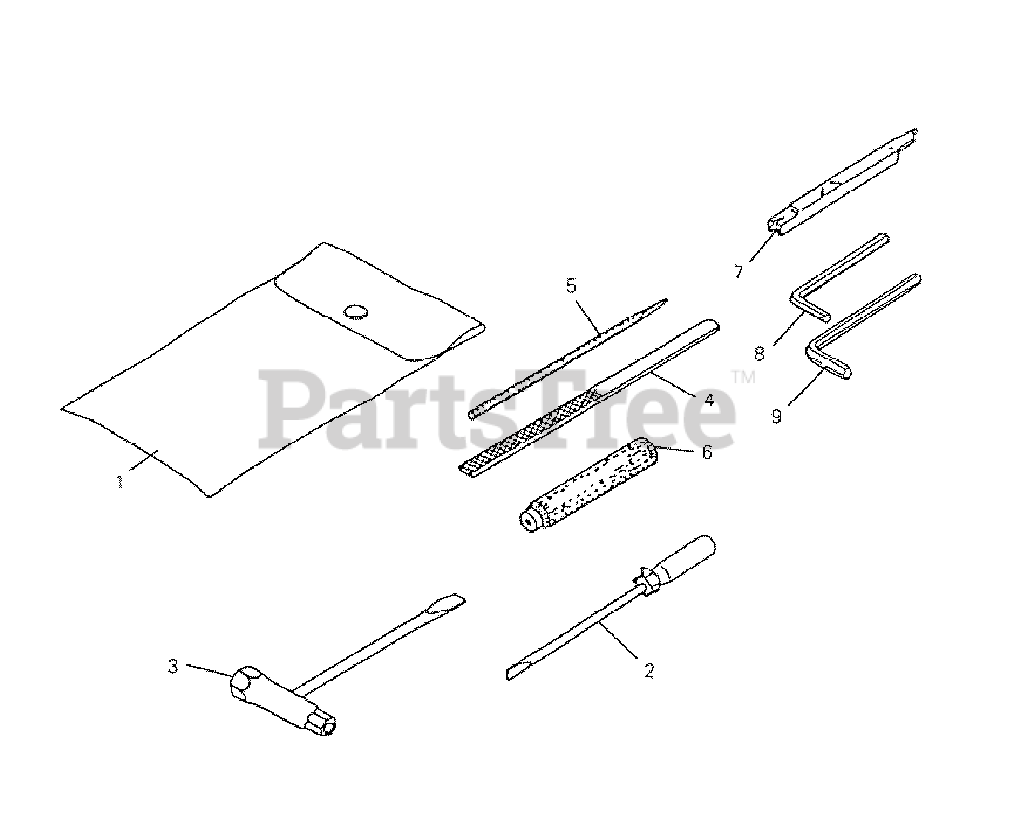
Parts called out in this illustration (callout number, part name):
1	BAG, TOOL
2	SCREWDRIVER
3	T-WRENCH 13×19 MM
4	FLAT FILE
5	ROUND FILE
6	GRIP
7	GAUGE
8	WRENCH, ALLEN 3 MM
9	WRENCH, ALLEN 4 MM
